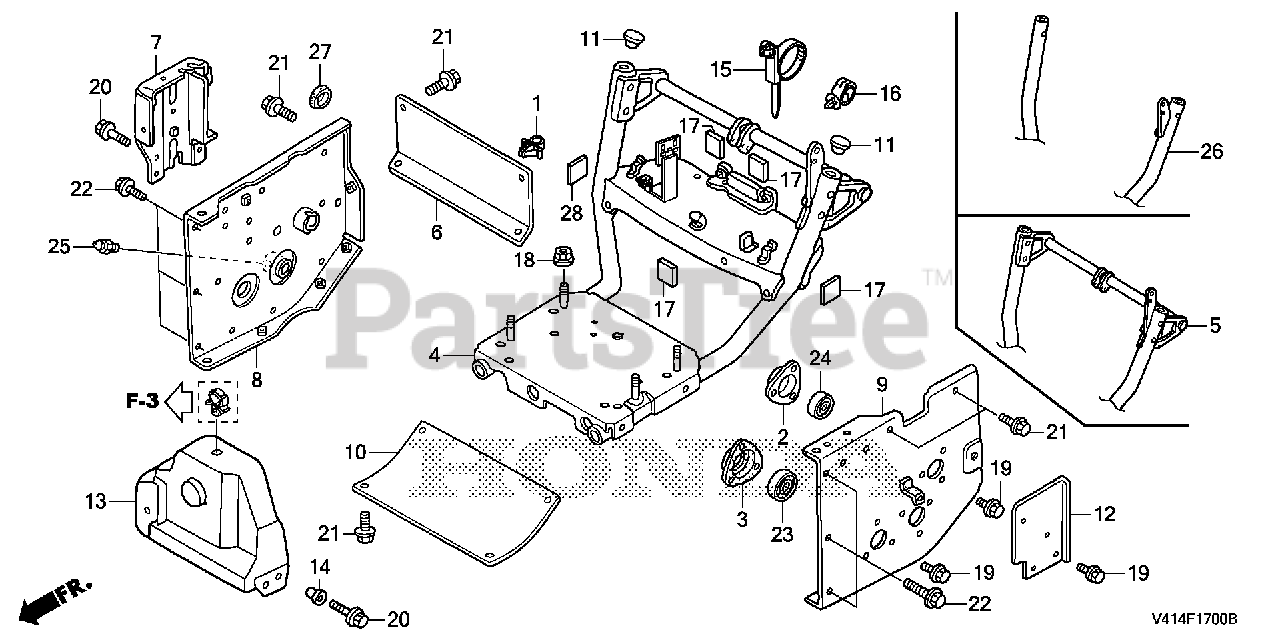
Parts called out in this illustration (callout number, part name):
2	HOLDER, BEARING
3	HOLDER, WHEEL SHAFT BEARING
6	STAY, ENGINE BED
7	HOLDER, WIRE
8	STAY, R. ENGINE BED
9	STAY, L. ENGINE BED
10	STAY, ENGINE BED (B)
11	CAP, HANDLE (LOWER)
13	COVER, BELT
14	WASHER, CHAIN CASE SETTING
18	NUT, FLANGE (10MM)
19	BOLT, FLANGE (6X12) Use up to Engine SN 1543277.
20	BOLT, FLANGE (6X14)
21	BOLT, FLANGE (8X12)
22	BOLT, FLANGE (8X16) Use from Engine SN 1000016.
23	BEARING, RADIAL BALL (6004UU)
24	BEARING, RADIAL BALL (6201UU)
26	BED, ENGINE
